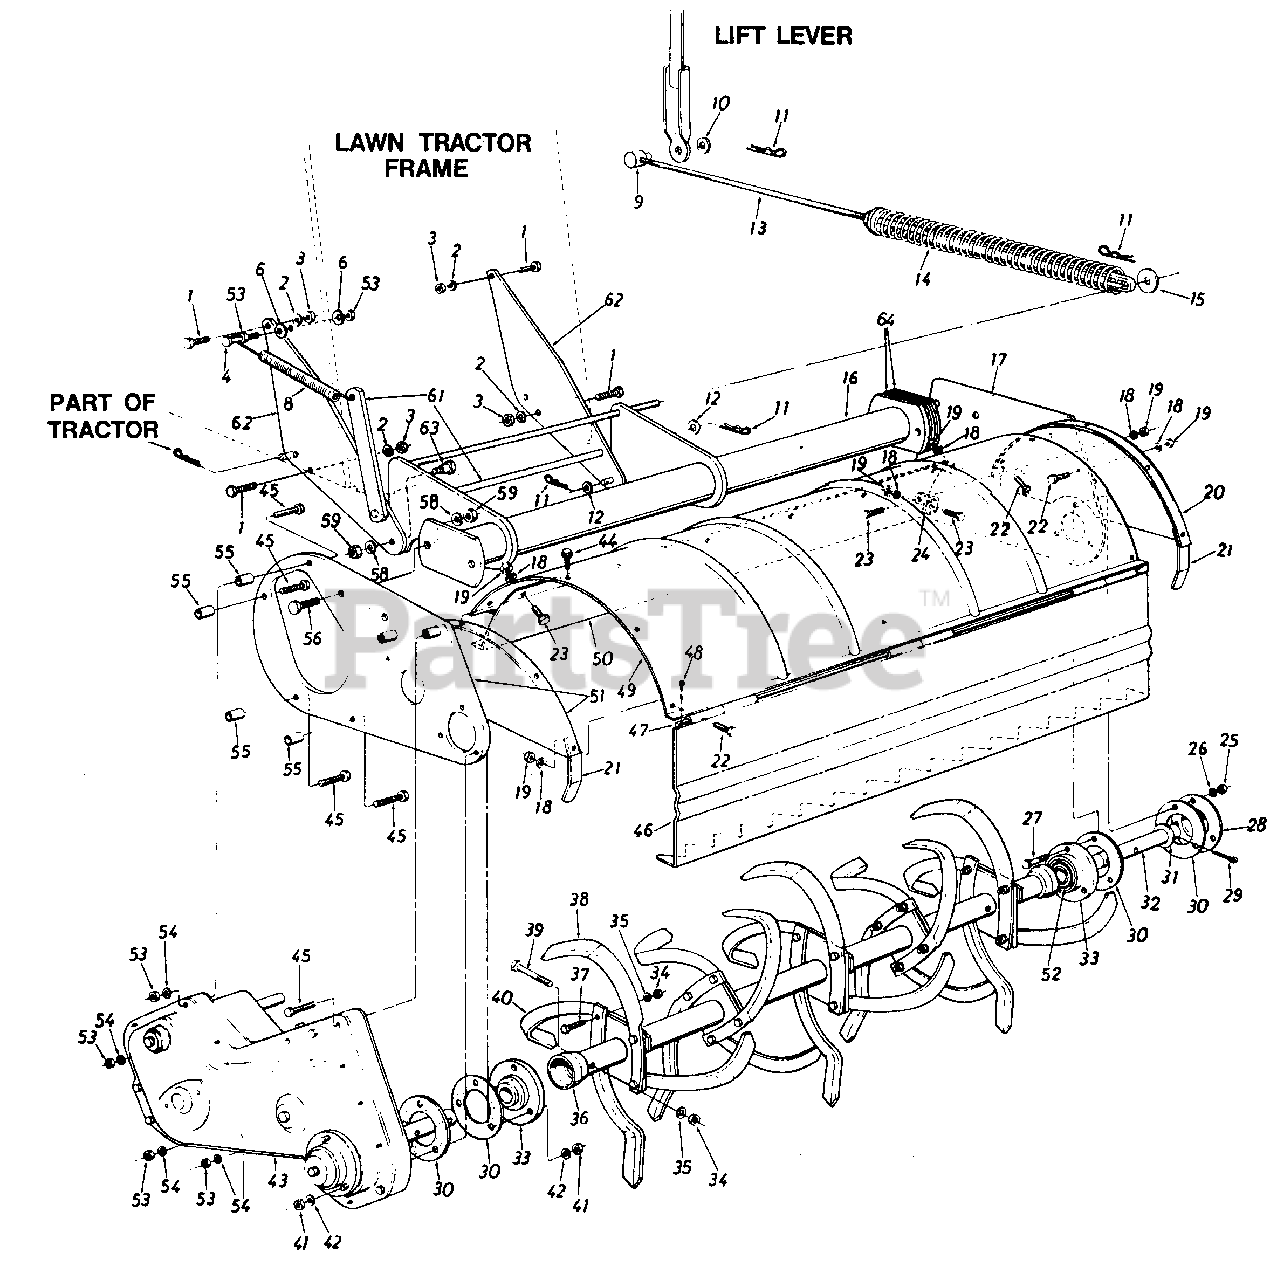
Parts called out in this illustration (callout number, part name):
1	Hex Bolt 3/8-24 x .88" Lg.
2	L.-Wash. 3/8" I.D. Heavy Duty
3	Hex Nut 3/8-24 Thd.
4	Hex Bolt 1/4-20 x 1.25" Lg.
6	Bell-Wash 1/4" I.D.
7	Hex Bolt 5/16-24 x 1.00" Lg.
8	Extension Sprinq 56" O.D. x 7.75" Lg.
9	Adjustment Ferrule 1/2-13 Thd.
10	Fl.-Wash. .640" I.D. x 1.24" O.D. x .060
11	Intern. Cotter Pin 1/2" Dia.
12	Fl.-Wash. .510" I.D x 1.0" O.D. x .060
13	Lift Rod Ass'y. 39.0" Lg.
14	Compression Spring 1.50" O.D. x 15.0" Lg.
15	Fl.-Wash. .51" I.D. x 1.50" O.D. x .075
16	Pivot Bracket Assembly
19	Hex Nut 5/16-24 Thd.
23	Hex Bolt 5/16-24x.62" Lg.
24	Chute Pivot Bracket
25	Hex Cent. L.-Nut 5 6-18 Thd.
26	L.-Wash. 5/16" I.D.
27	Hex Bolt 5/16-18 x 1.0" Lg. (Grade 5)
30	Gasket for Brg. Housing
31	Fl.-Wash. 1.25" I.D. x 2.00" O.D. x .06
32	Tine Shaft R.D. 1.25" Dia. x 6.25" Lg.
33	Bearing Housing w/Bearing
34	Hex Nut 3/8-24 Thd.
35	L.-Wash. 3/8" I.D. Heavy Duty
41	Hex Cent. L.-Nut 5/16-18 Thd.
42	L.-Wash. 5/16" I.D.
43	Chain Case Ass'y. Comp.
44	Hex Wash. TT Tap. Scr. 5/16-18 x .62" Lg.
45	Hex Bolt 1/4-20 x 2.75" Lg.
48	Cotter Pin 1/8" Dia. x 1.00 Lg.
53	Hex Nut 1/4-20 Thd.
54	L.-Wash. 1/4" I.D.
55	Spacer .28" I.D. x .62" O.D. x .90" Lg.
56	Hex Bolt 1/2-20 x 1.5" Lg.
58	L.-Wash. 1/2" I.D.
59	Hex Jam Nut 1/2-20 Thd.
61	Idler Bracket Support Arm Ass'y.
64	Support Plate
